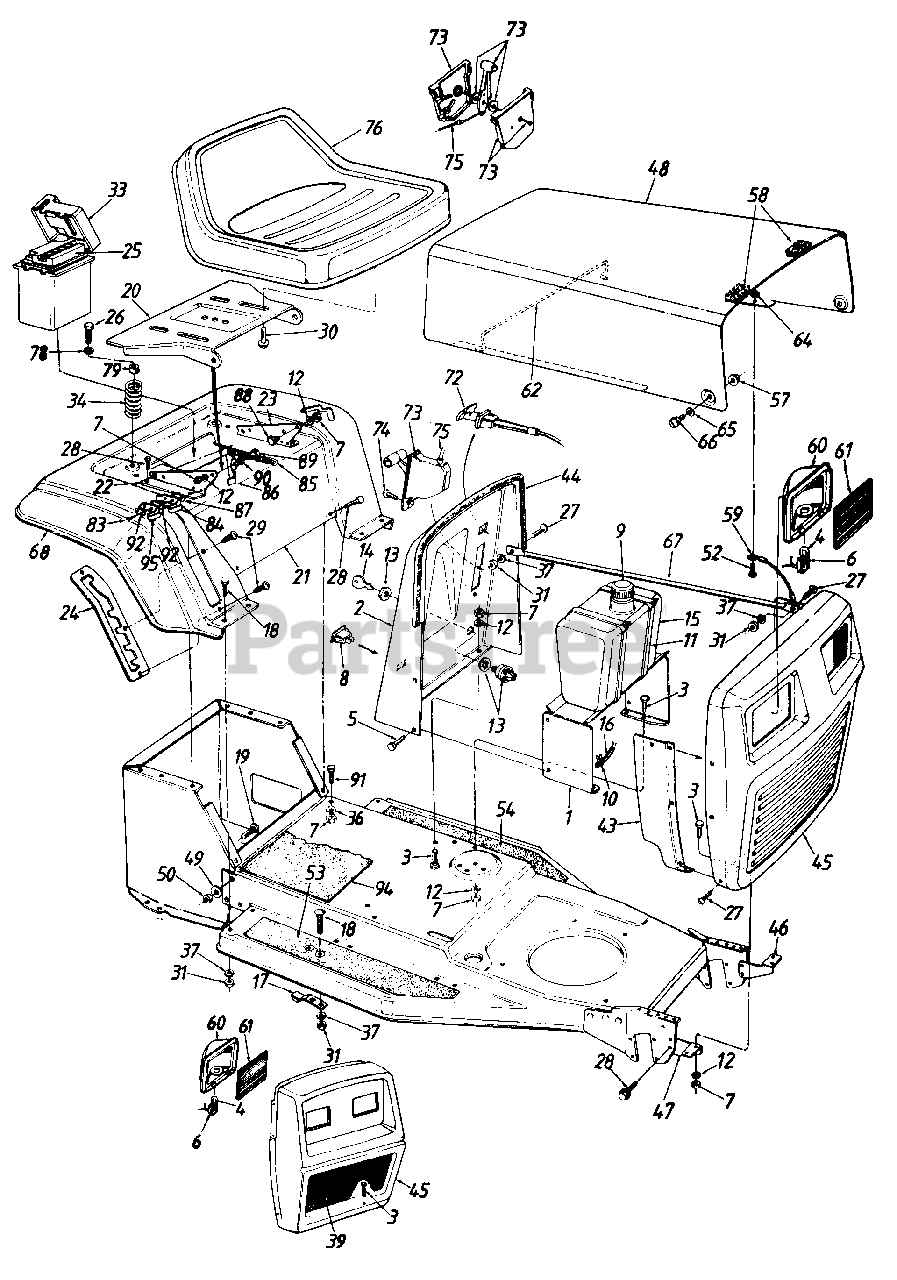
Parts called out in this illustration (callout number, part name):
1	Dash Panel Support Brkt.
4	Bulb
5	Hex AB-Tap Scr. 1/4 x .62"
6	Socket
7	Hex Nut 5/16-18 Thd.
8	Light Switch
9	Gas Cap
10	Hose Clamp
11	Cable Tie
12	L-Wash. 5/16" I.D.
13	Ignition Switch
14	Ignition Key
15	Fuel Tank
16	Gas Line 15" Long
17	Blade Brake Ass'y.
18	Carriage Bolt 1/4-20 x .62"
19	Ribbed Neck Bolt 3/8-24 x .8"
20	Seat Pivot Brkt.
25	Battery
26	Hex Self-Tap Screw 5/6-18 x 1.25" Lg.
27	Truss Mach. Scr. 1/4-20 x .75" Lg.
28	Hex AB-Tap Scr. 5/16 x .75" Lg.
29	Torx Mach. AB-Tap Scr. 1/4 x .62" Lg.
30	Hex Self-Tap Scr. 3/8-16 x .75" Lg.
31	Hex Nut 1/4-20 Thd.
33	Battery Box w/Cover
34	Compression Spring
36	Bell-Wash. 5/16" I.D.
37	L-Wash. 1/4" I.D.
39	Grille Insert
44	Trim Strip 31" Lg.
47	Grille Mtg. Brkt.-R.H.
50	Hex L-Nut 3/8-24 Thd.
52	Truss Mach. Scr. #10-24 x .5" Lg.
53	Foot Pad-R.H.
54	Foot Pad-L.H.
57	Lock Nut 1/4-28 Thd.
58	Foam Strip
59	Hood Stop
60	Headlight Housing
61	Lens
62	Hood Spring
64	Hex Sems Nut #10-24 Thd.
65	Spr. Wash. .39" I.D. x .62" O.D.
66	Shld. Bolt
67	Grille Support
68	Trim Strip 81" Lg.
72	Choke Control
73	Throttle Control Box
74	Truss AB-Tap Scr. #10 x .5"
75	Throttle Wire
76	Seat Assembly
78	Fl-Wash. .344" I.D. x .88" O.D.
79	Bushing
83	Hex Tap Scr. #8 x .51' Lg.
84	Safety Switch
85	Ext. Spring 5.31" Lg.
86	Seat Lift Brkt.
87	Insulator Boss Plate
88	Shld. Bolt .437" Dia. x .162" Lg.
89	Shld. Bolt .437" Dia. x .268" Lg.
90	Spr. Wash. .445" I.D. x .75" O.D.
91	Hex Wash. Hd. Scr. 5/16-18 x .62" Lg.
92	Insulator Plate
94	Center Foot Pad
95	Safety Switch
